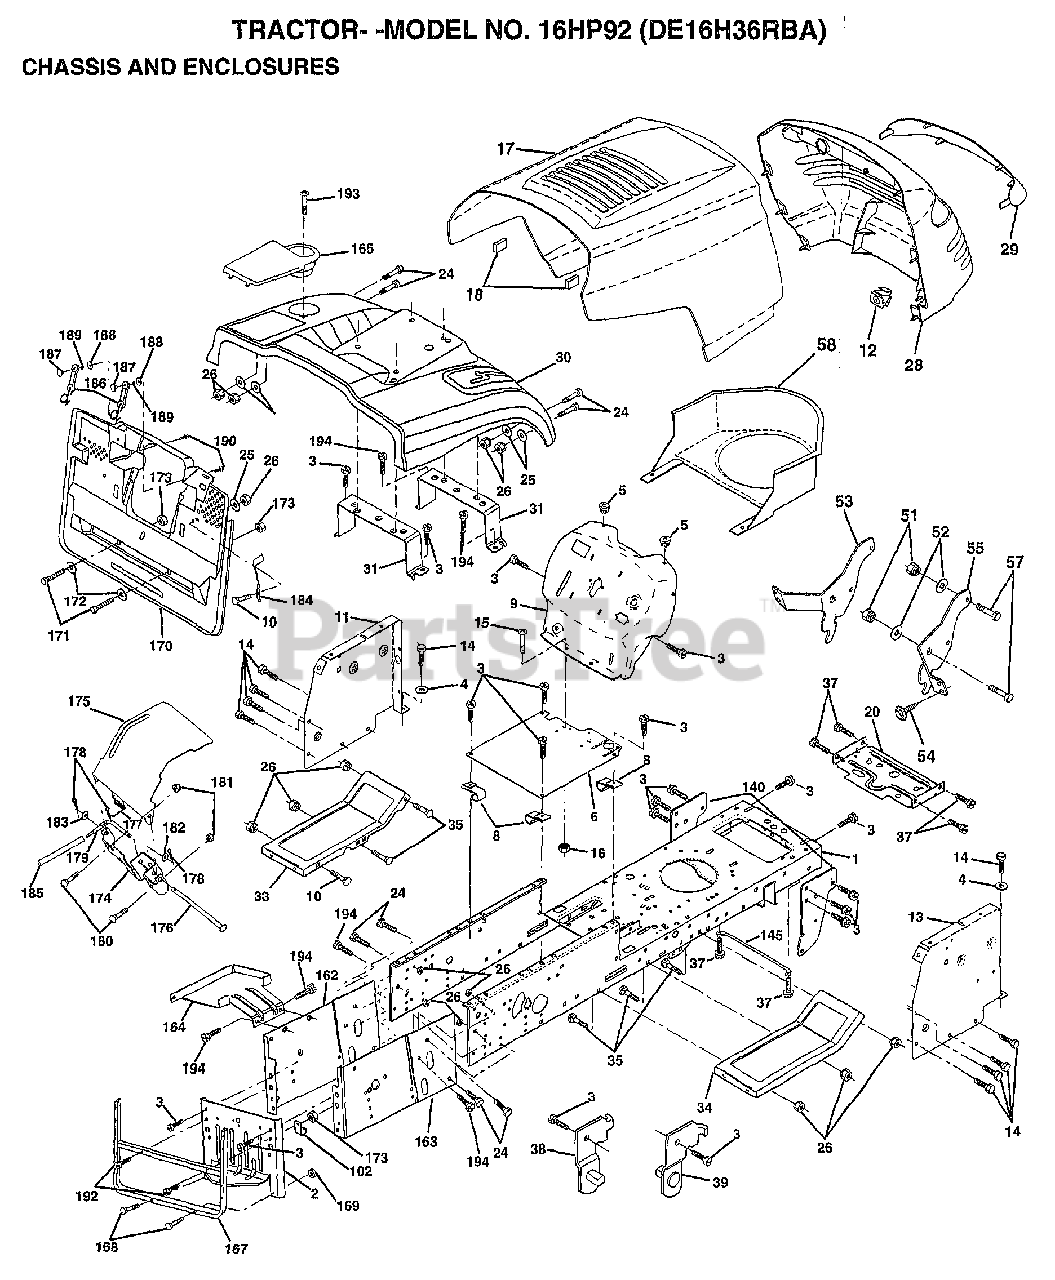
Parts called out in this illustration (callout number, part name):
1	CHASSIS.STAMPING
2	DRAWBAR.CRD
3	SCREW
4	WASHER
5	BUMPER-HOOD/DASH
6	SADDLE
8	"CLIP,INSULATOR"
9	DASH.SILKSCREEN
11	"PANEL-DASH,LH"
12	CLIP.TINNERMAN
14	SCREW LT
15	SCREW
20	"PLATE-MTG,BATT/FU"
24	BOLT
25	WASHER
26	NUT
28	GRILL
30	FENDER.CRD.SAGE
31	BRKT.SUPT.FENDER.CRD
33	FOOTREST
34	FOOTREST.PNT.RH
35	BOLT
37	SCREW LT
38	BRACKET ASM LH
39	BRACKET ASM RH
51	NUT
52	WASHER
53	BRACKET.GRILLE.LH
54	SCREW.HEX.WS.HD
55	BRACKET.GRILLE.RH
58	AIR DUCT
102	CLIP T
140	BRKT SUSPENSION
145	"ROD POVOT,CHASSIS"
162	BRKT.EXT.CHASSIS.LH.CRD
163	BRKT.EXT.CHASSIS.RH.CRD
164	SUPPORT.BATTERY.CRD
165	COVER.BATTERY.CRD.BLACK.LT
167	SUPT.ASM.BACKPLATE
168	BOLT-RD HD SQ NK
170	COVER.BACKPLATE.BLACK
171	BOLT.HEX.3/8-16X2-1/2
173	NUT
174	BRKT.SWITCH.FBI.CRD
175	GRUARD.DOOR.REAR.CRD
176	HINGE PIN
177	SPRING.COVER.LH
179	ROD.PIVOT.FBI.CRD
182	WASHER.385X.625
183	WASHER
184	BRKT.ACTUATOR.BAG.CRD
185	TUBE.LEVER.SWCH.FBI.CRD
186	LATCH ASSY.BAGGER
187	WELDNUT
188	WASHER #10
189	LOCKWASHER
190	SCREW
192	SCREW LT
193	SCREW LT
194	SCREW
